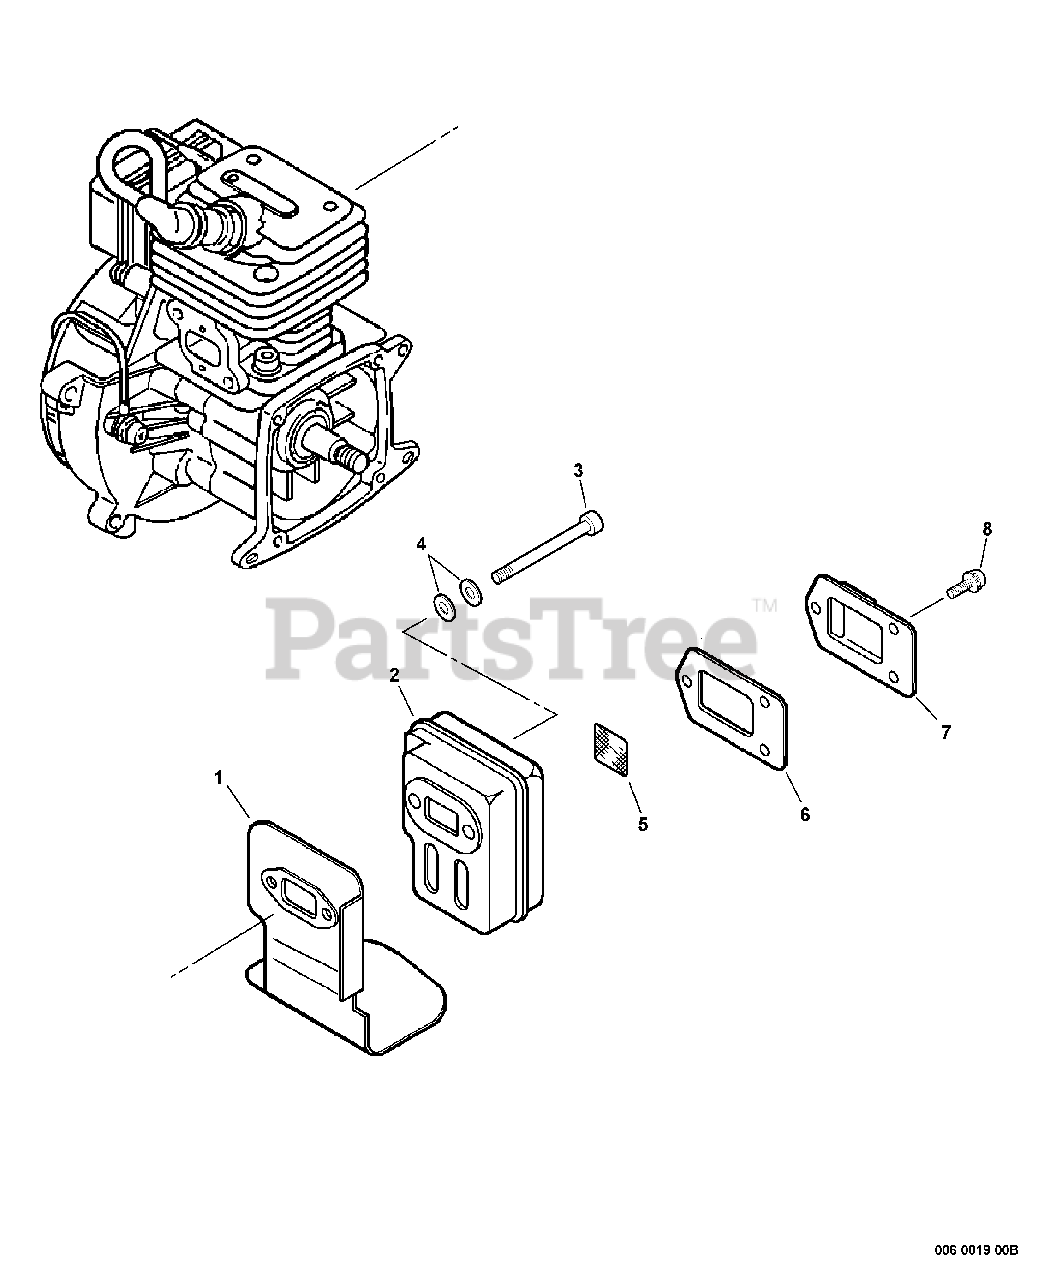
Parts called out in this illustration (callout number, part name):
1	SHIELD, EXHAUST
3	SCREW - 5X55
4	WASHER - 5
5	SCREEN, SPARK ARRESTOR
6	GASKET, EXHAUST
7	GUIDE, EXHAUST
8	SCREW - 4X12
